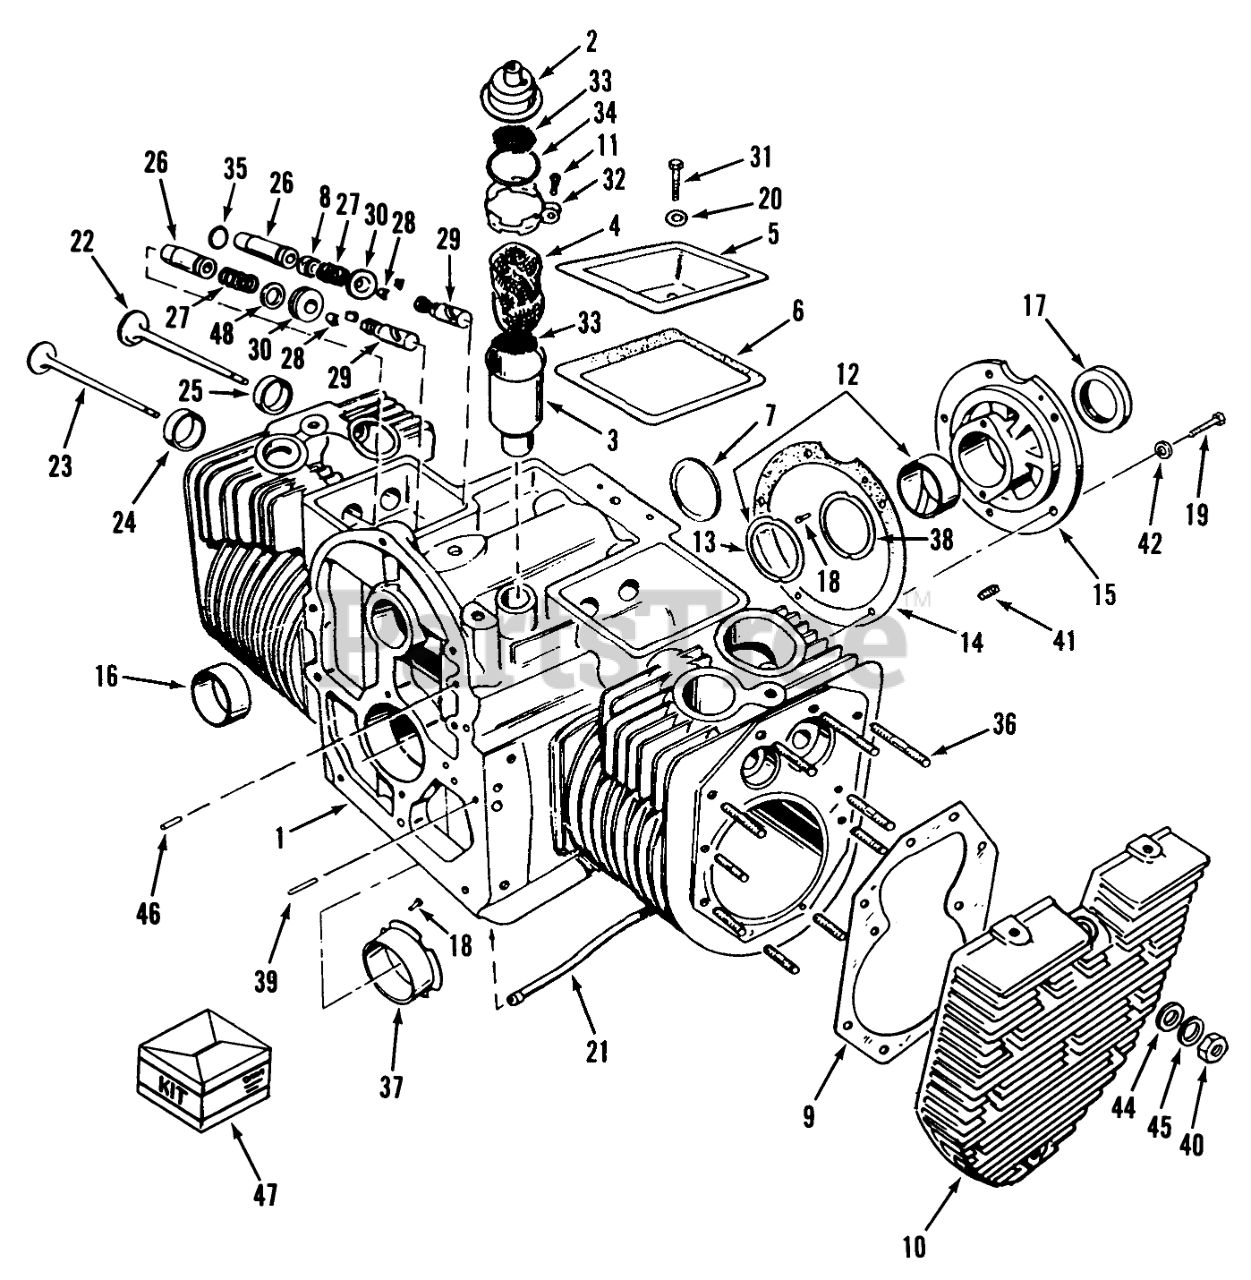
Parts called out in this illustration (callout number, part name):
1	SHORT-BLOCK (T-260)
2	Breather Cap & Valve
3	Breather Tube
4	Baffle
5	VALVE COMPARTMENT
6	Valve Cover Gasket
7	Plug
8	Intake Valve Seal
9	Cylinder Head Gasket
10	Cylinder Head
11	Screw #8 x 3/4
12	Rear Crankshaft Bearing-STD
13	ThrustWasher
14	Gasket
15	Bearing Plate
16	Camshaft Brg
17	Oil Seal
18	Screw
19	SPRING LOCKWASHER
20	Washer
21	Crankcase Oil Tube
22	INTAKE VALVE
23	EXHAUST VALVE
24	Exhaust Seat Insert-Std
25	Intake Seat Insert-STD
26	Exhaust Valve Guide
27	Spring-Valve
28	Valve Spring Lock
29	Tappet
30	Rotator-Valve
31	Bolt 1/4-20 x 2
32	Clamp
33	Screen
34	Seal
35	Intake Valve Guide Gasket
36	Mtg. Stud-Cylinder Hd (Install 4 Bottom Holes LH, RH Hd)
37	Standard
38	Shim 0.005"
39	Pin
40	Nut
41	Screw
42	Lockwasher 3/8
44	Washer
45	O-Ring
46	Plug
47	Gasket Kit-Carbon Removal
48	Washer
